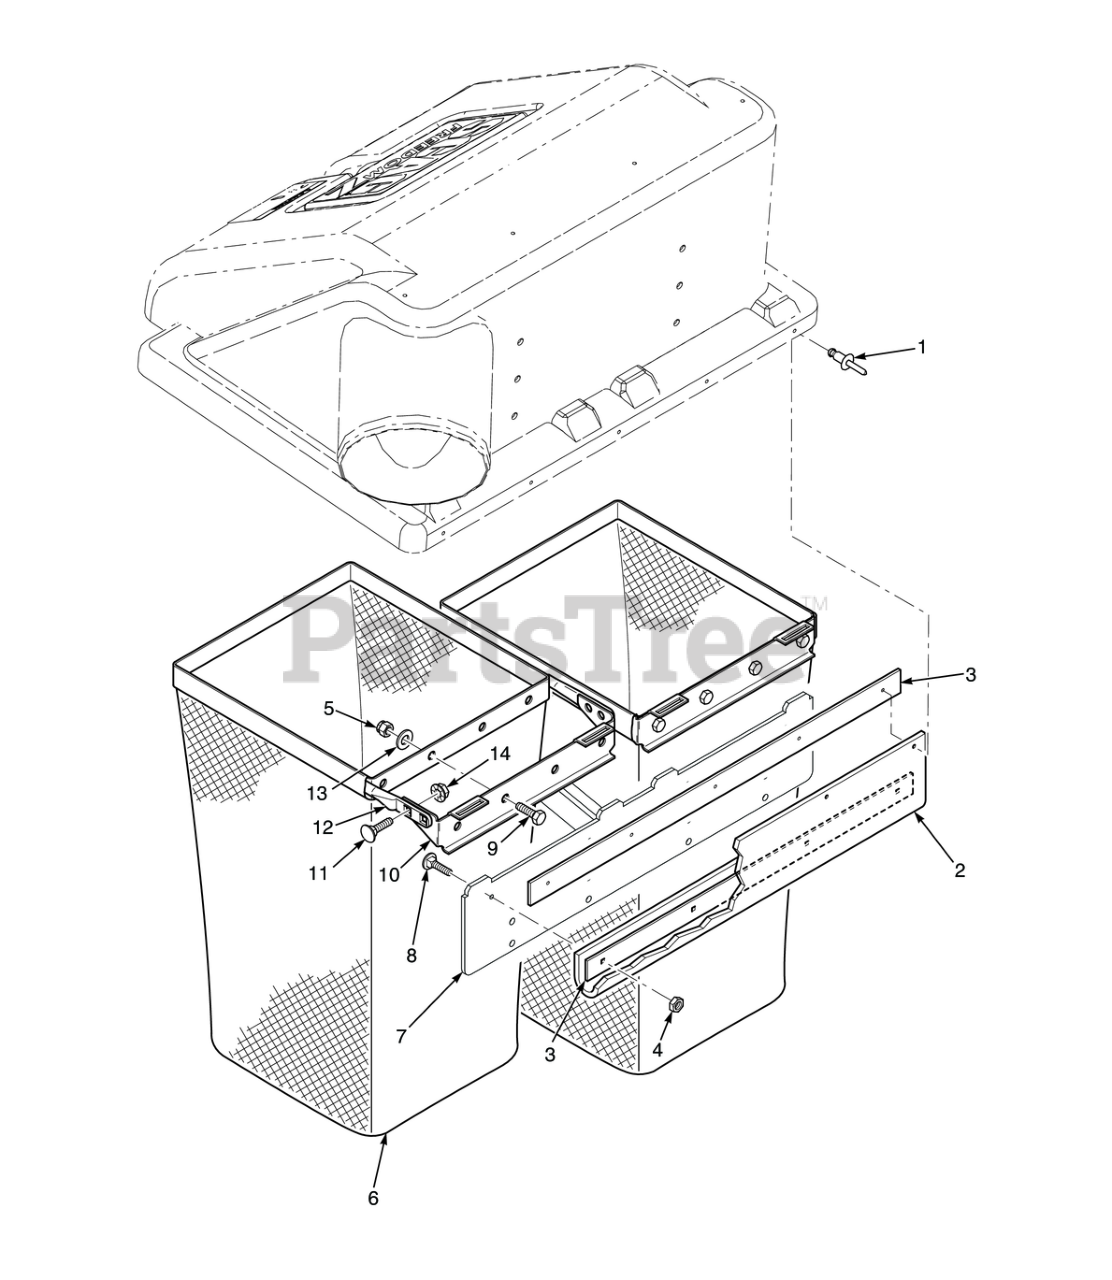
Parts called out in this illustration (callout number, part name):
1	Pop Rivet, 3/16 x .652"
2	Diode (part of wire harness)
3	Retainer, Seal
4	Bolt, Hex Hd. 1/2-13 x 9-1/2"
5	HEX NUT, ELASTIC STOP LOCK, 5/16-18
6	Bag Assembly
7	Frame Weldment, Bag Support
8	BOLT, HEX HEAD, 1/4-20 X 3/4 GR.5
9	BOLT, SERRATED FLANGE HEX HEAD 5/16-18 X 3/4"
10	Mount, Bag Frame Tube
11	Bolt, 5/16-18 x .75 RHSN Carriage
12	Tube, Bag Support
13	Flatwasher, 5/16-.375 x .875 x .083 (35BV & 37BV-EFI)
14	Nut, Serrated Flange 5/16-18 (Right Front Engine Mounting, Briggs and Kohler Only)
